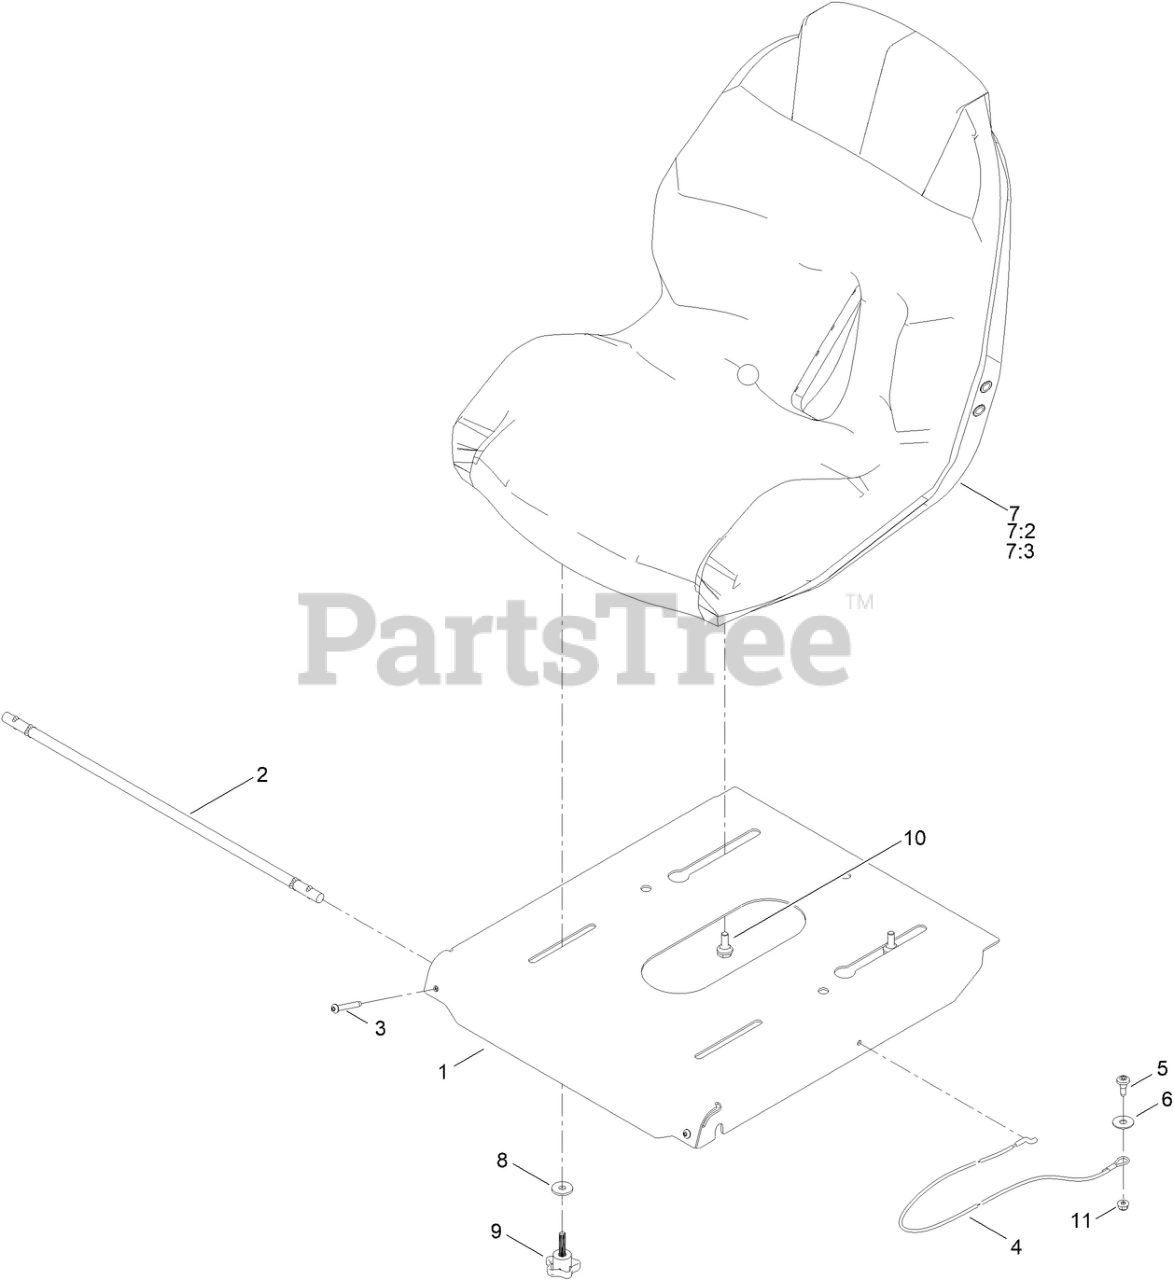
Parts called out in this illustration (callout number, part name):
1	PAN-SEAT
2	ROD-PIVOT
3	SCREW-TBH,THD ROLL
4	CABLE-LANYARD, 26.75"
5	SCREW-SHOULDER
6	WASHER-FLAT
7	SEAT ASM - SEAT KING SK130
7:2	COVER-SEAT
7:3	SWITCH-BAIL
8	WASHER-FRICTION
10	BOLT-SHOULDER,HFH
11	NUT-FLANGE, NI
